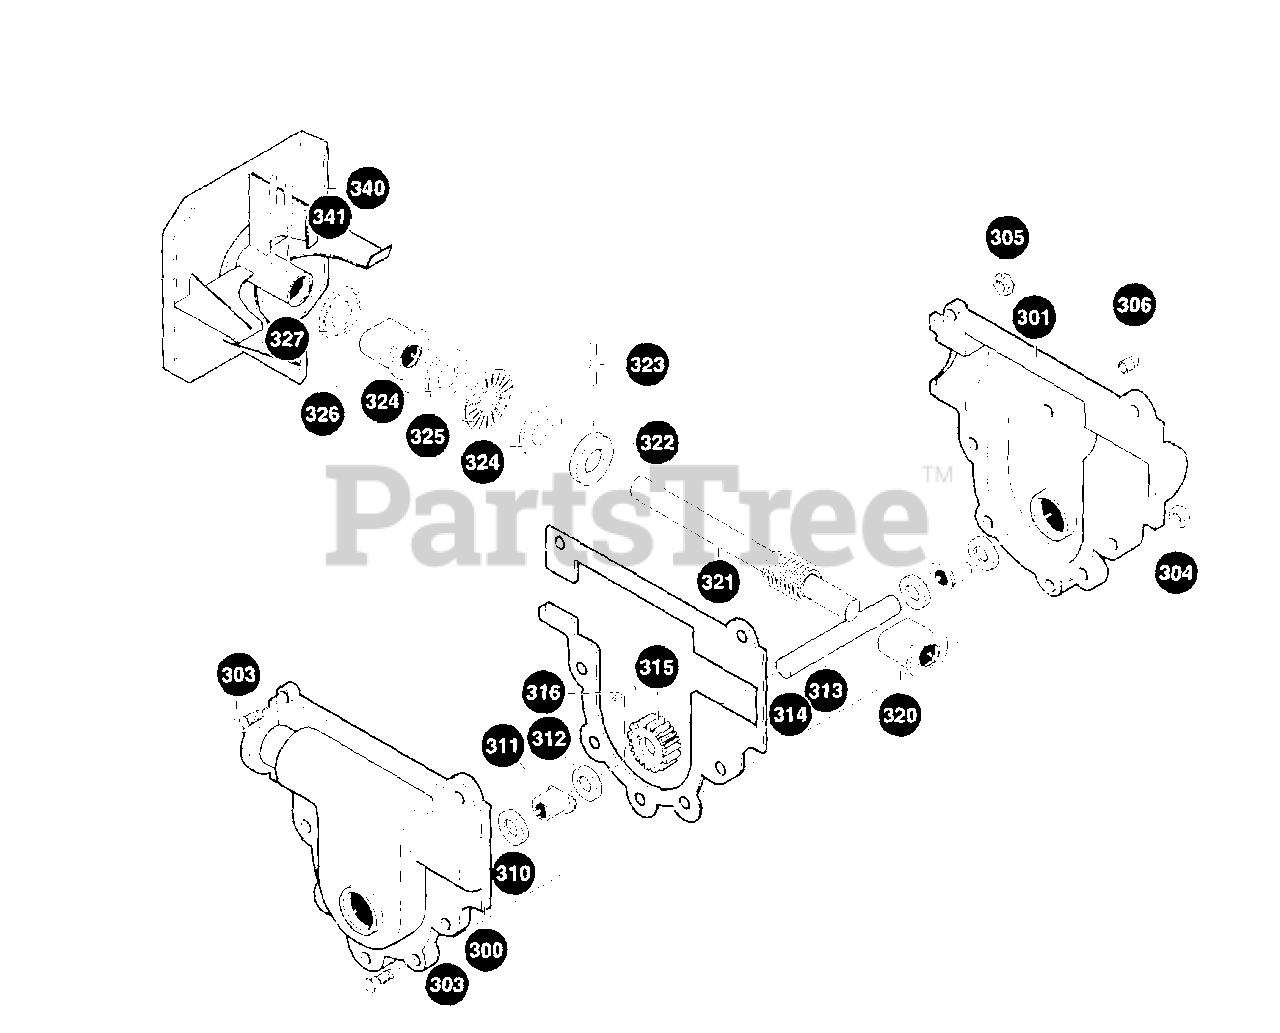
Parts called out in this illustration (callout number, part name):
300	Gear Case, RH
301	Gear Case, LH
303	Screw, 1/4-20 x .75
304	Nut, 1/4-20
305	Nut, 1/4-20 Hexkeps
306	Screw, 3/8-16 x .50
311	Bearing, Flange
312	Flatwasher, .752 x 1.24 x .093
313	Shaft, Auger Output
314	Gasket, Gear Case
315	Gear, Worm
316	Key, Woodruff
320	Bearing, Flange
321	Shaft, Worm Imp Input
322	Collar, Thrust .753 x 1.24 x .50
323	Pin, Spring
324	Flatwasher, .752 x 1.24 x .093
325	Bearing, Roll
326	Bearing, Flange
340	Impel, Assy
341	Spring Pin
